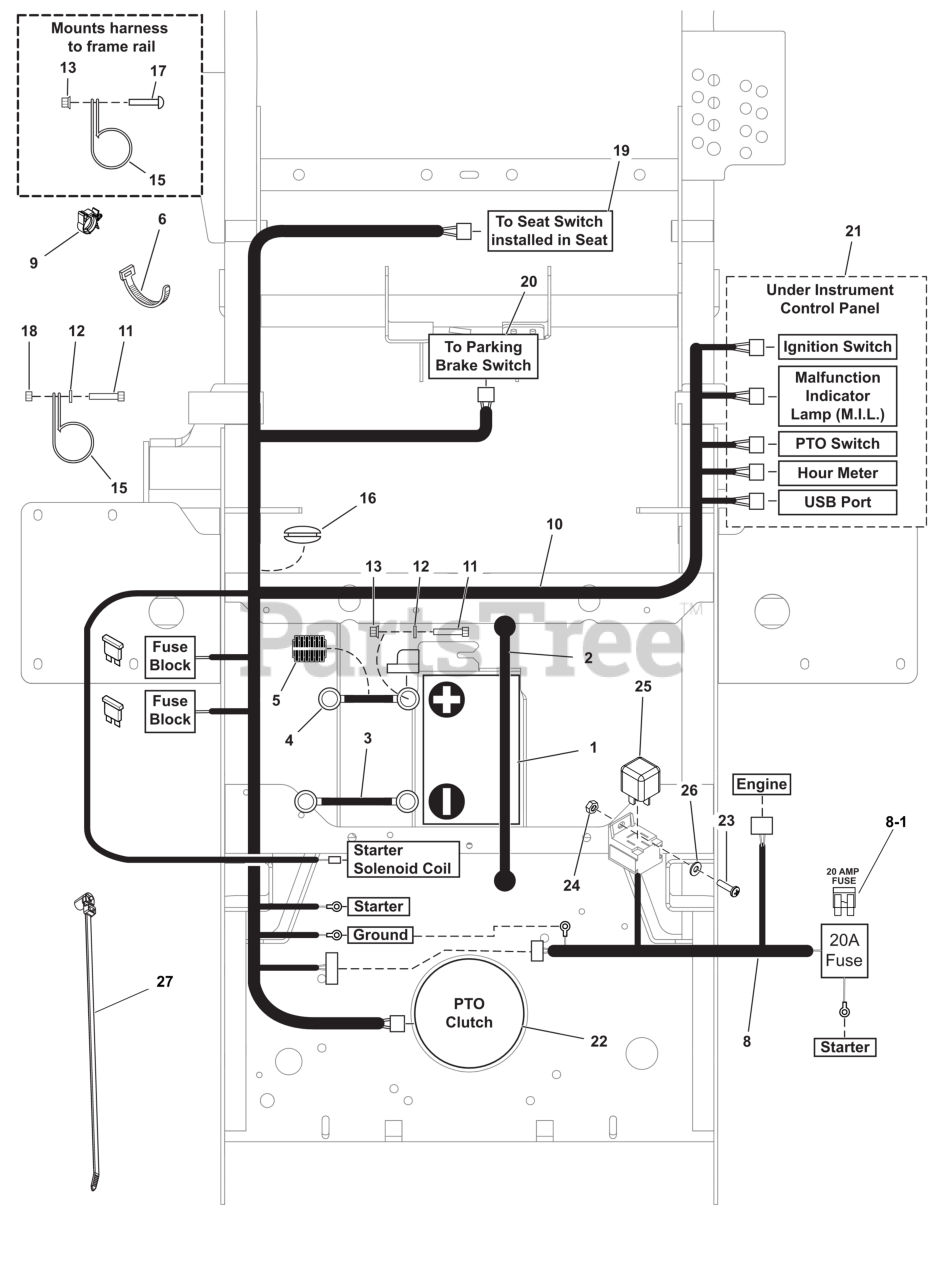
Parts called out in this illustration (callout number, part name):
1	BATTERY, 11U1L, 350 CCA
2	STRAP
3	BATTERY CABLE, NEGATI
4	BATTERY CABLE, POSITI
6	TIE, Cable 11" Long
8	HARNESS, Wiring
8-1	FUSE, ATO, 20 AMP
10	HARNESS, Wiring
11	BOLT, 1/4-20 X 3/4" G
12	WASHER
16	GROMMET, 1-1/2" ID FOR 1/4" METAL
19	Refer to: Seat Mount & Floor Group
20	Refer to: Parking Brake Group
21	Refer to: Instrument Control Panel Group
22	Refer to: Engine & PTO Group
23	SCREW - #10-24
25	RELAY, 12V, 40A
26	WASHER, Rivet, 3/16
27	CABLE, Tie (Sold as a bag of 5)
